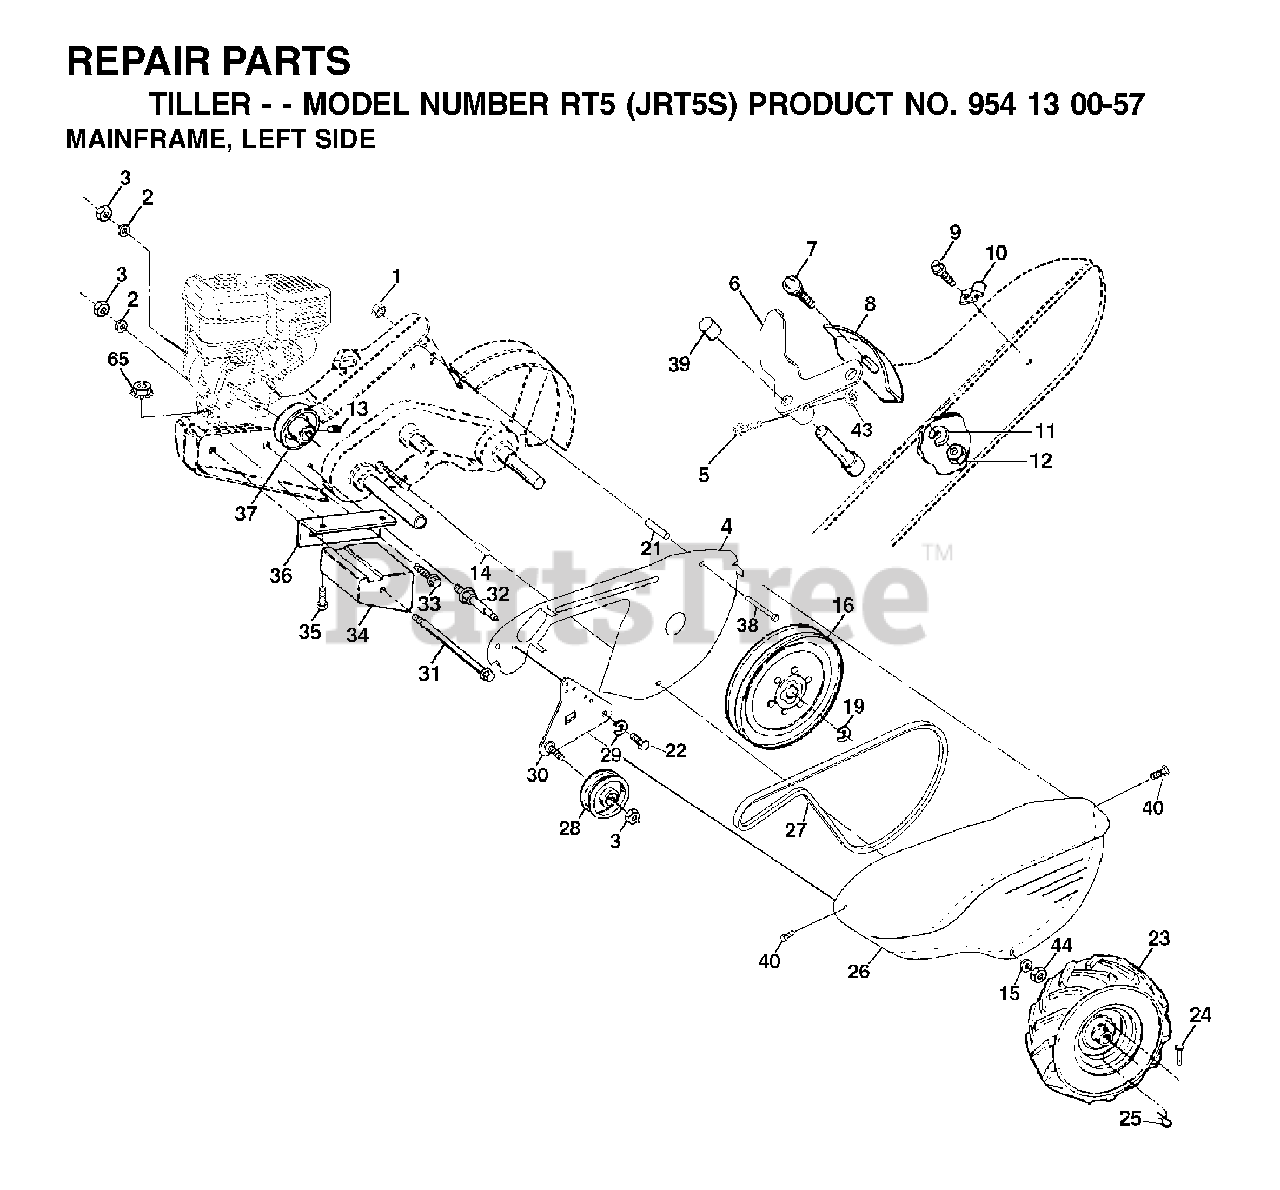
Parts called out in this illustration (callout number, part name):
1	NUT
2	WASHER, LOCK 3/8
3	NUT.HEX.3/8-16UNC
5	SCREW, SHIFT LEVER
6	LEVER ASM CRT
9	TAPPING SCREW
10	CONDUIT CLIP T
11	LOCKWASHER
12	NUT
13	SET SCREW **
14	SPACER-SPLIT.327 X .42
15	WASHER
16	SHEAVE, TRANSMISSION
19	RETAINING RING LT
21	SPACER CRT
24	RIVET,DRILLED
25	RETAINER M
27	V-BELT
28	PULLEY-IDLER TI
29	KLIP RING
30	BRACKET.ASM.IDLER
31	BOLT.FIN.HEX.3/8-16UNC
32	SHIFT ARM CRT
33	BOLT
34	COUNTERWEIGHT.LH.CRT
36	BRACKET LH CRT
37	ENGINE PULLEY
38	BOLT
39	CAP.PLUNGER.BLACK
40	SCREW.HEX.WSH.SLT.#10-24X.50
44	NUT.71038.31-18.HEX.NYLOCK
65	LOCKNUT-FLANGE 5/16-18
5321243-66	RIM
5321247-18	VALVE STEM LT
